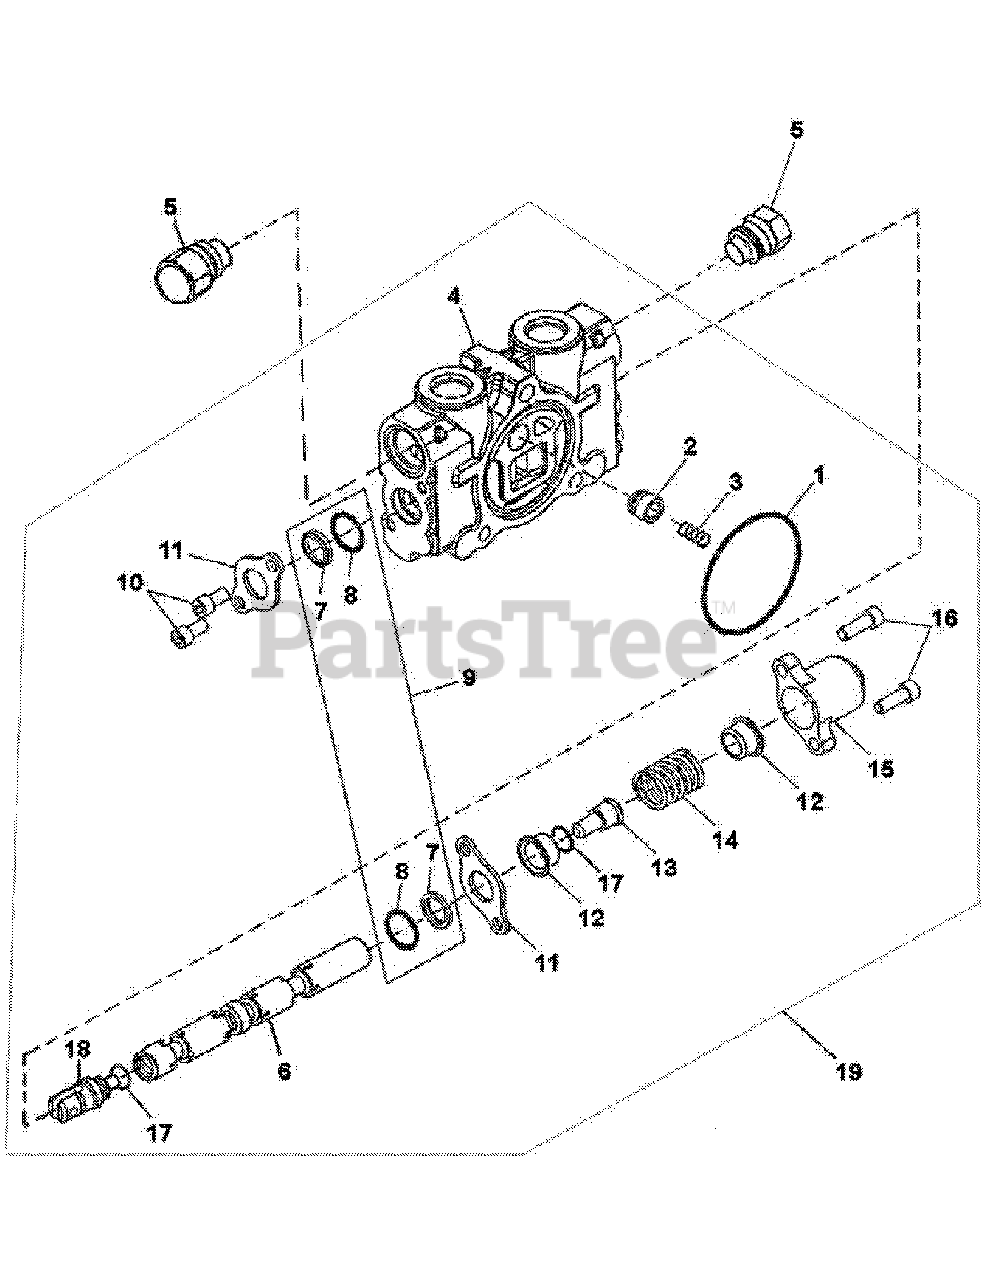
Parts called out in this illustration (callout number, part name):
1	O-Ring
2	Poppet, Load Check
3	Spring, Load Check
4	Valve Section
5	Plug, Shut-Off
7	Wiper, Spool
8	O-Ring, Spool
9	Seal Kit, Minor (contains two of Item 7 & 8)
10	Cap Screws, Socket Head
11	Plate, Retainer
12	Seat, Spring
13	Screw, Spring Seat
14	Spring, Spool Centering
15	Cap, Spring Spool
16	Cap Screws, Socket Head
17	O-Ring
18	Clevis End
19	Valve Section Assembly (less Item 5)
20	Seal Kit, Major
21	Load Check Poppet Kit
22	Spring Centered Spool Positioner Kit
